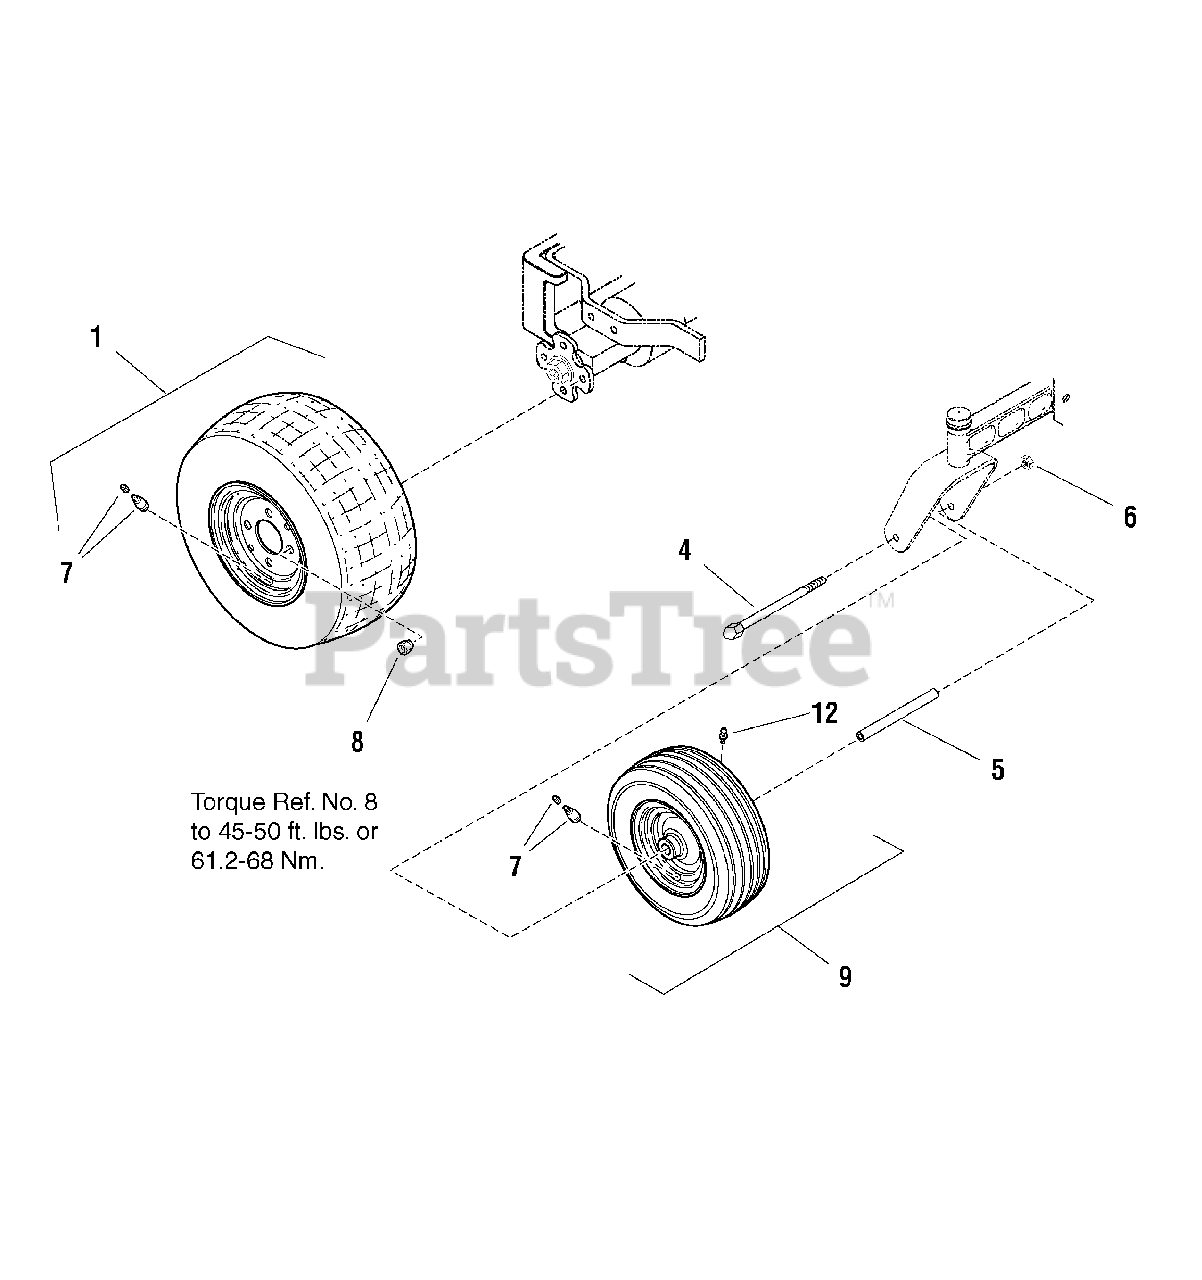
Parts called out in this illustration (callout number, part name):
1	WHEEL & TIRE ASSEMBLY, 18 x 8-1/2-8
2	WHEEL, 18 x 8-1/2 - 8
3	TIRE, 18 x 8-1/2 - 8
4	CAPSCREW, Hex Head
5	TUBE, Caster Wheel Spacer
6	NUT, Hex Center Lock
7	VALVE STEM & CAP
8	NUT, Hex Lug, 7/16-20
9	WHEEL & TIRE ASSEMBLY, 11 x 4-5
10	WHEEL, 11 x 4 - 5
11	TIRE, 11 x 4 - 5
12	FITTING, Lube
